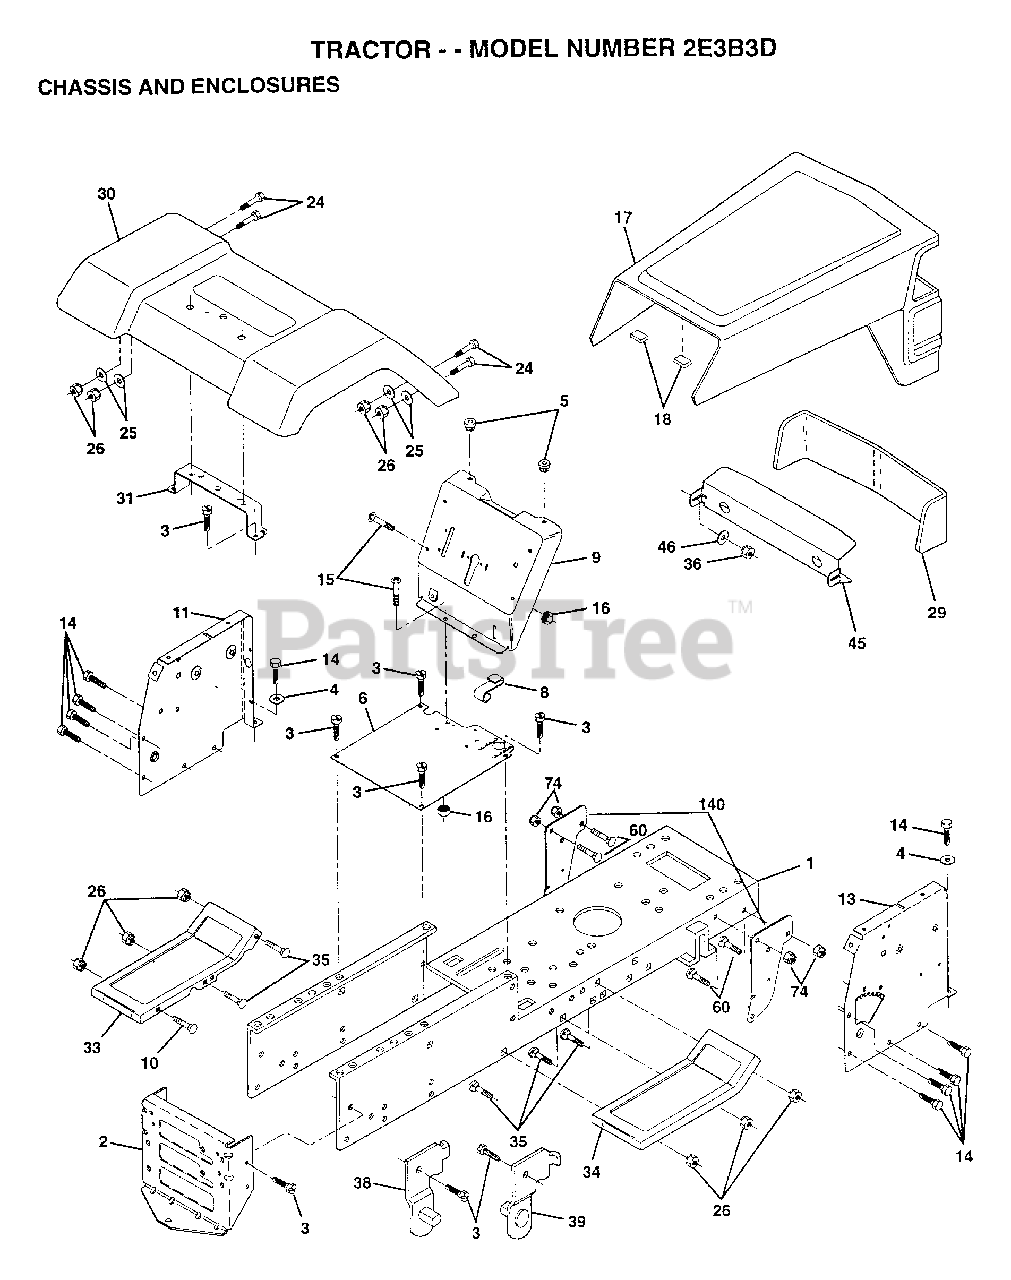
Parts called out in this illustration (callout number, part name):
1	CHASSIS WLDMT 11G
3	SCREW
4	WASHER
8	"CLIP,INSULATOR"
9	DASH.SLKSC.LT.1PC
11	PANEL.DASH.LH.
14	SCREW LT
15	SCREW
17	HOOD/GRILL ASM
24	BOLT
25	WASHER
26	NUT
30	FENDER
31	BRKT FENDER
33	FOOTREST LH
34	FOOTREST RH
35	BOLT
36	PAL NUT LT
38	BRACKET ASM LH
39	BRACKET ASM RH
46	RETAINER
60	BOLT
